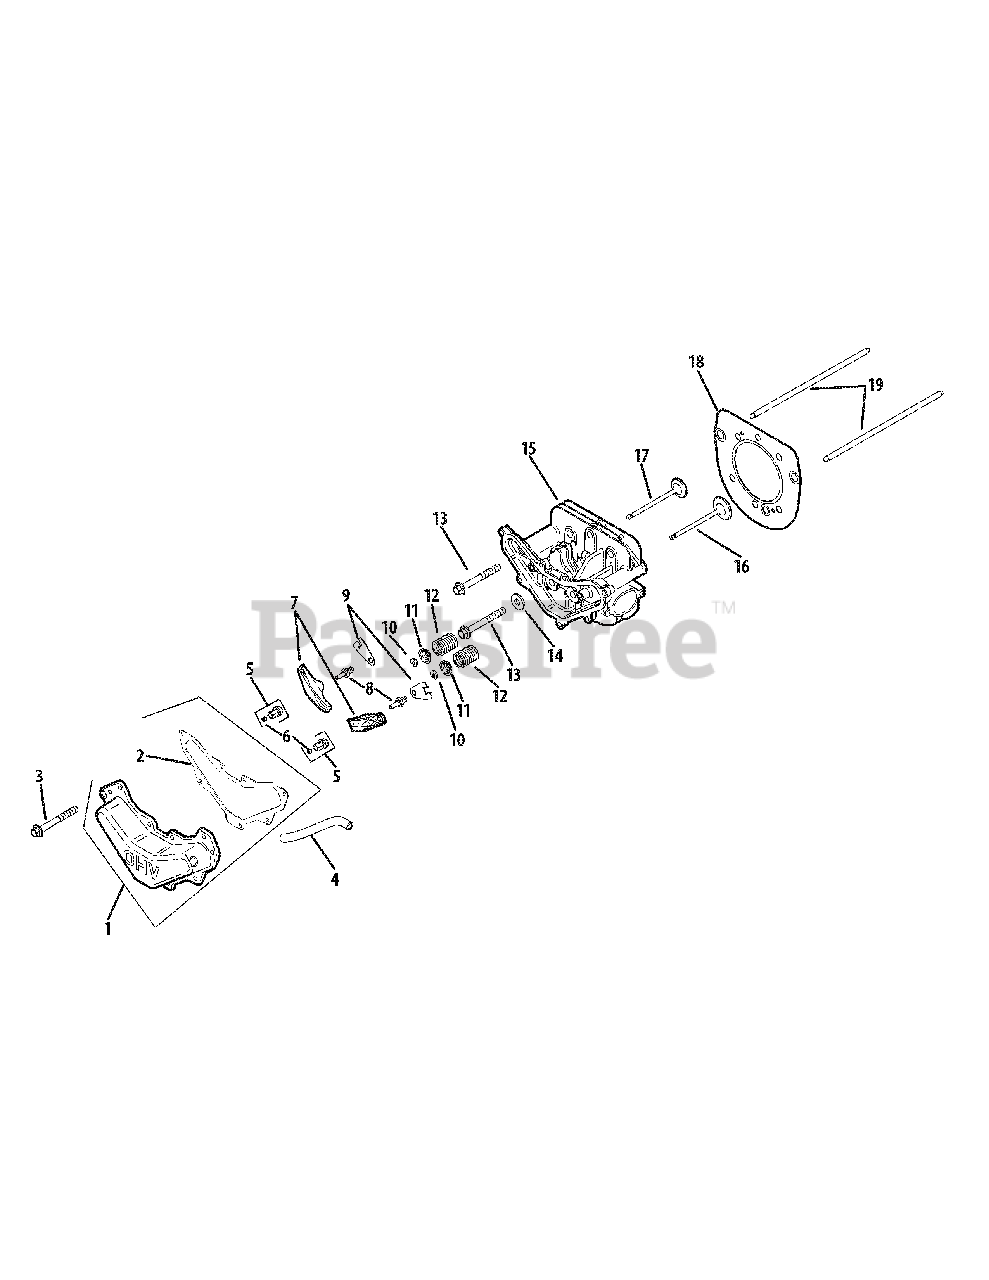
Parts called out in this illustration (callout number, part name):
1	Valve Cover Kit (Inc. 2)
2	Valve Cover Gasket
3	Flg Thd Frm Screw, M6 x 1.0 x 20
4	Breather Hose
5	Rocker Arm Pivot (Inc. 6)
9	Push Rod Guide Plate
10	Retainer Lock
11	Valve Spring Cap
13	Flg Screw, M10 x 1.5 x 80
14	Flat Washer, 13/32"
15	Cylinder Head Assembly
16	Exhaust Valve
18	Cylinder Hd. Gasket (Inc. 2, 13 & 14)
19	Push Rod
